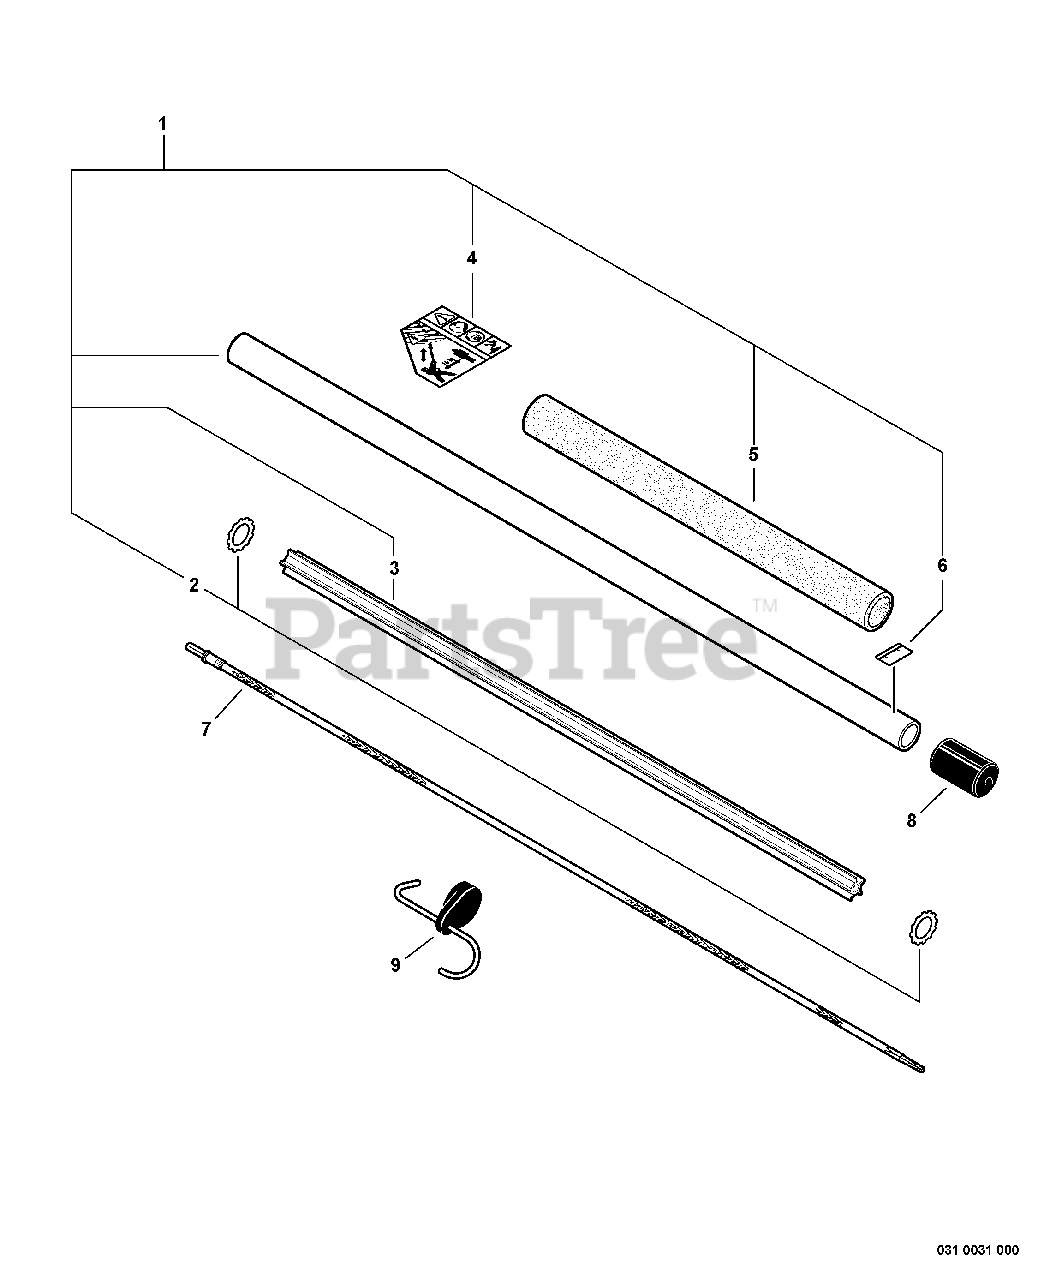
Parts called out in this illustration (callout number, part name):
1	MAIN PIPE ASSY
2	LOCKWASHER - EXTERNAL
4	LABEL - CAUTION
5	GRIP, HANDLE
6	LABEL - ALIGNMENT
7	DRIVESHAFT - FLEXIBLE
9	PAS ATTACHMENT HANGER
